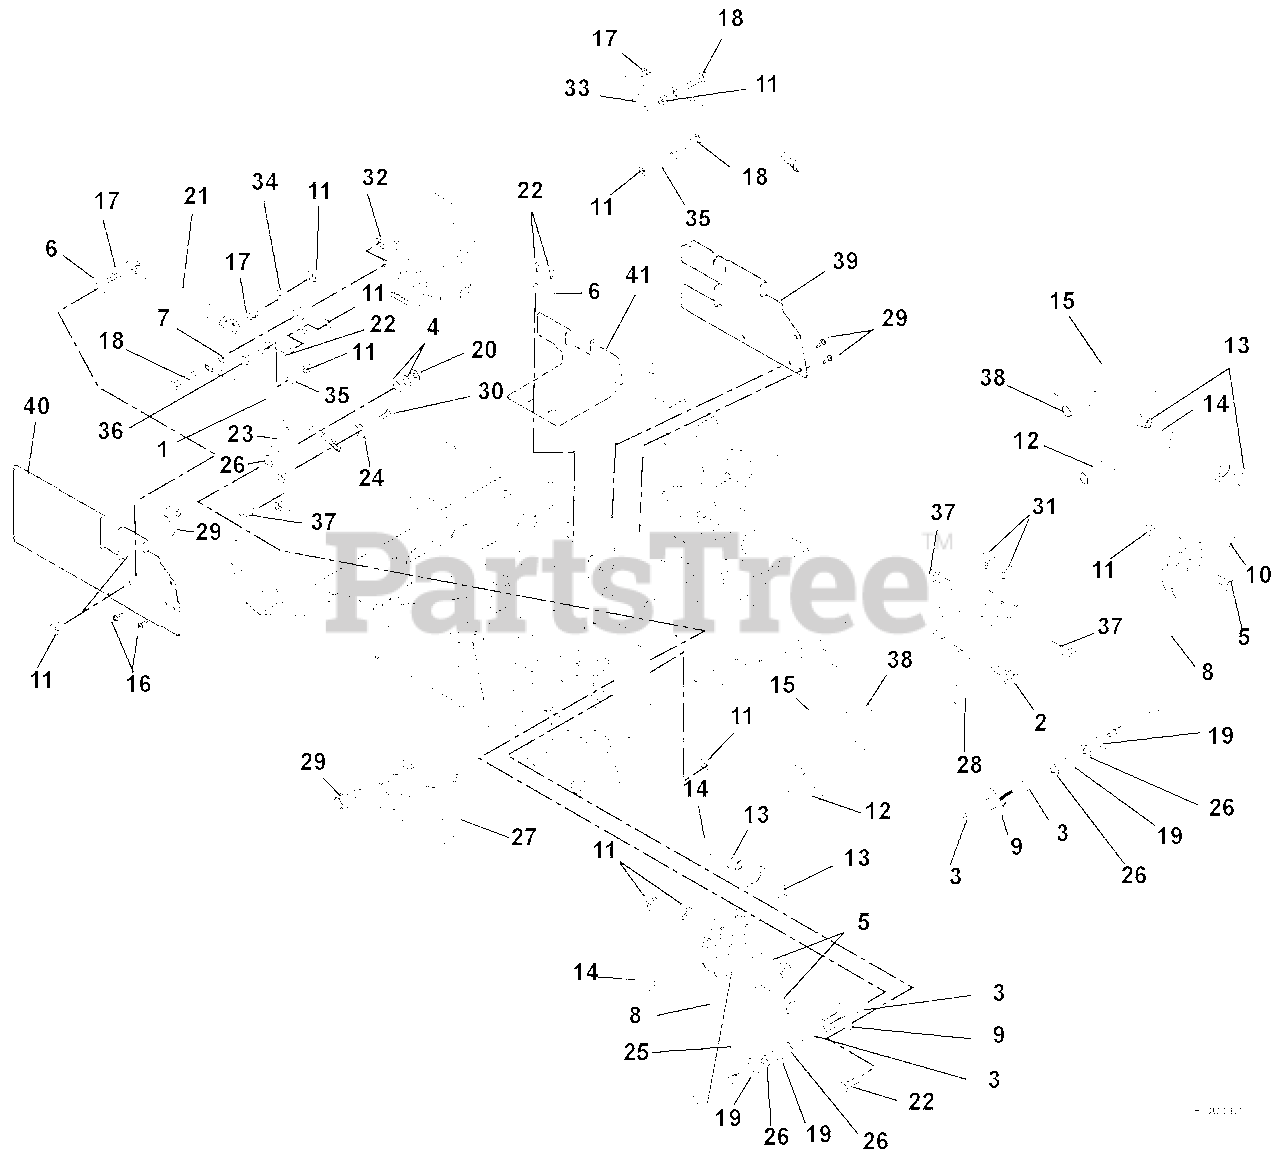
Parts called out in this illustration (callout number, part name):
1	Assembly, Steering Rod .38 Rod x 7.60
2	Screw, Tapping .Hex Washer Head 38-16 x .75
3	Bushing .625 x .75 x .50
4	Washer, Flat Steel .403 x .812 x .065
5	Bolt, Hex .31-18 x 1.75 Grade 5
6	Washer, Flat Steel .344 x .688 x .065
7	Nut, Hex .38-16
8	Control Arm
9	Bushing, Flange
10	Bushing, Eccentric .31 x .75 .97
11	Nut, Locking Top Flange .31-18
12	Handle Weldment, Left Hand
13	Bushing, Flange Nylon .762 x 1.48 x .44
15	Grip, Handlebar
16	Screw, Tapping Hex Washer Head .31-18 x .50
17	Stud, Ball
18	Bolt, Hex .38-16 x 1.50 Grade 5
19	Washer, Flat Steel .63 x 1.005 x .062
20	Nut, Locking Top Flange .38-16
21	Damper, Control
22	Bolt, Hex .31-18 x .75 Grade 5
23	Weldment, Pivot Arm
24	Washer, Locking .38 x .094 Regular
25	Key, Woodruff .13 x .63
26	Washer, Wave
27	Stop, Steering Right Hand
28	Stop, Steering Left Hand
29	Screw, Tapping Hex Washer Head .38-16 x .50
30	Bolt, Hex .38-16 x 1.25 Grade 5
31	Nut, Hex Jam .375-16
32	Nut, Locking Center .38-16
33	Bracket, Left Hand
34	Bracket, Right Hand
35	Spacer .318 x .43 x .375
36	Bolt, Hex .31-18 x 1.25 Grade 5
37	Bolt, Hex .375-16 x 1.75 Full Thread
38	Tube, .88ID x 1.00OD x 10.75
39	Bracket, Dampener Debris Shield Left Hand
40	Bracket, Dampener Debris Shield Right Hand
41	Shield, Debris Lower
